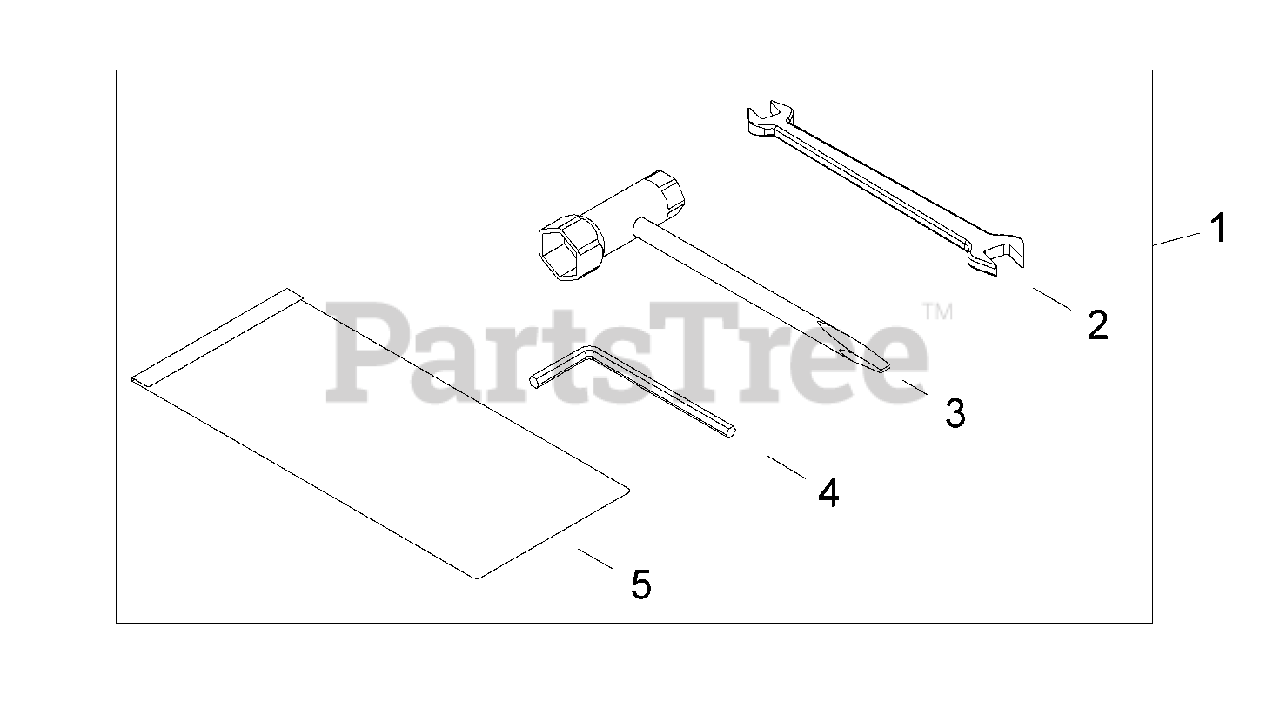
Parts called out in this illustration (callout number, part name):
1	TOOL KIT
2	SPANNER - 8X10mm
3	T-WRENCH - 13X16mm
4	HEX KEY - 4mm
5	BAG, TOOL
